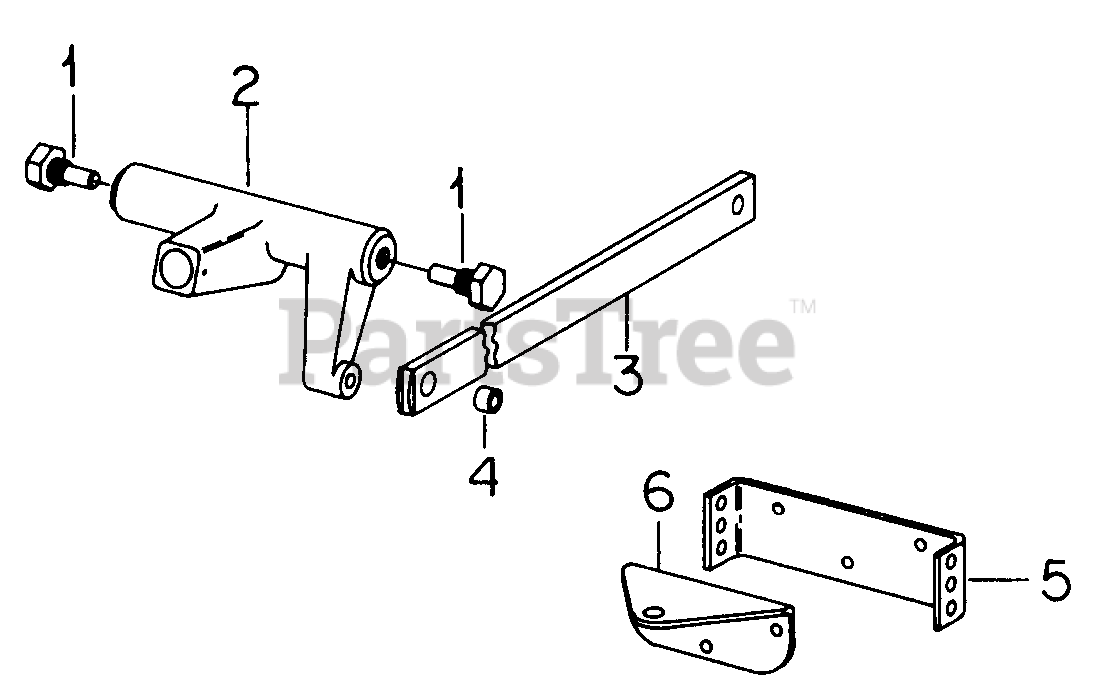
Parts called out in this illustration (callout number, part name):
1	Bolt, Stud Shaft
2	Lever, Lift
3	Bar, Lift
4	Spacer, Lift Arm
6	Drawbar, Fixed
